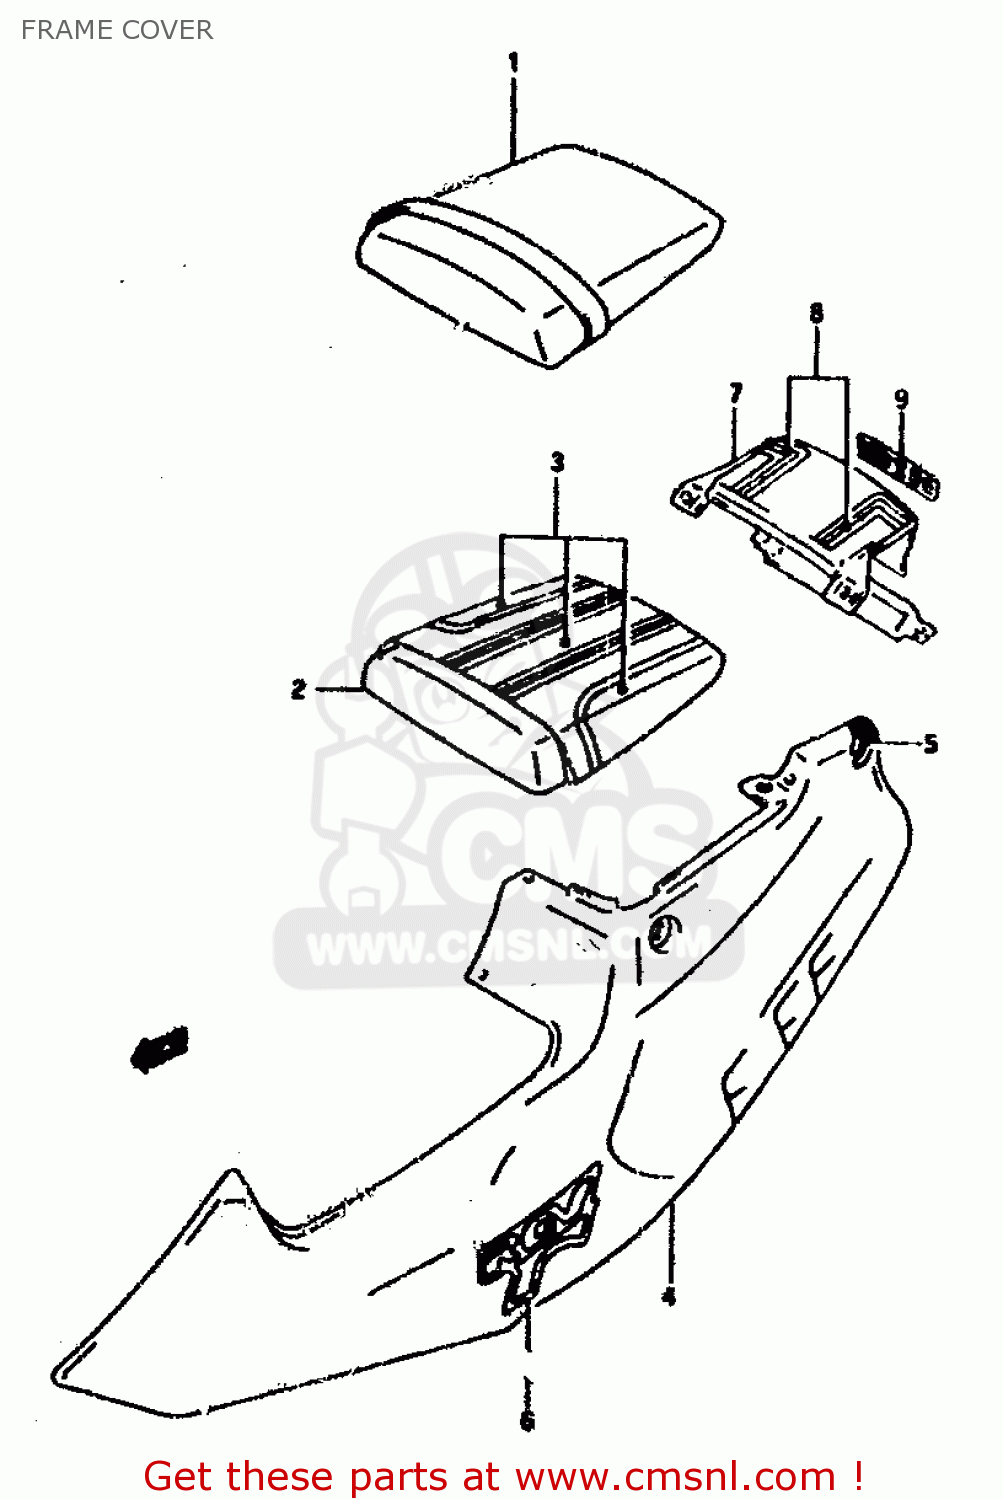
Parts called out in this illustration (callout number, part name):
1	SEAT ASSY, PILLION (BLACK)
2	BOX, SEAT TAIL
3	TAPE SET, TAIL BOX
4	COVER, FRAME RH
5	TAPE, FRAME COVER RH
6	EMBLEM, FRAME COVER
7	COVER, FRAME CENTER (WHITE)
8	TAPE SET, FRAME CENTER
9	EMBLEM
